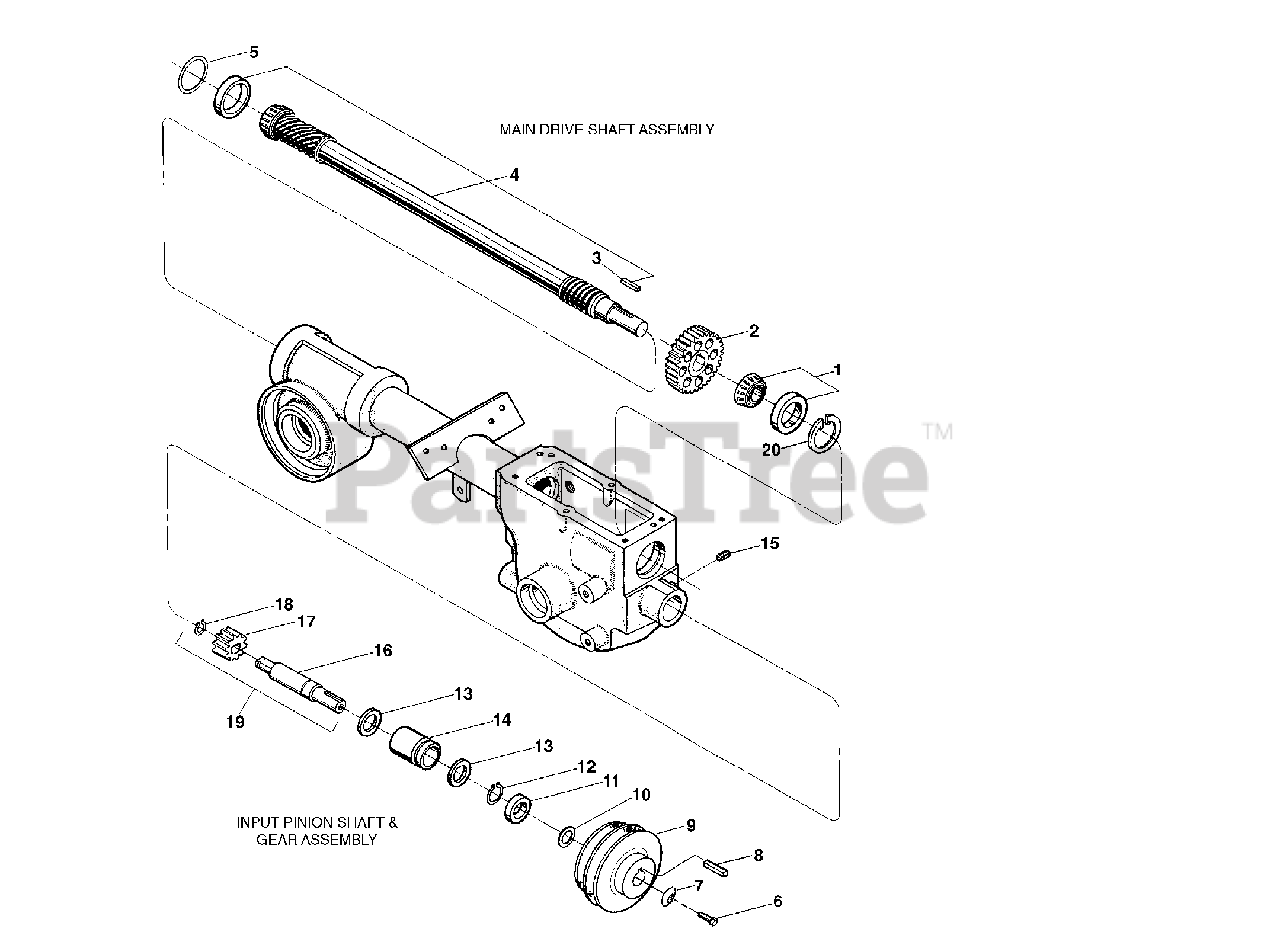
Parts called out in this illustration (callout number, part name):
1	Bearing, Tapered Roller with Race
2	Spur Gear
3	Key, 3/16 sq. x 1
4	Main Drive Shaft
5	Shim, Rear Bearing Cap, .010" thick
5	Shim, same as above, but .030" thick
5	Shim, same as above, but .005" thick
6	Hex Hd. Screw, 5/16-24 x 1-1/8
7	Washer, Disc Spring (concave surface faces pulley)
8	Key, 3/16 sq. x 1-1/2
9	Transmission Drive Pulley
10	Support Washer
11	Oil Seal, Input Pinion Shaft
12	Retaining Ring (external)
13	Thrust Washer
14	Bushing
15	Set Screw, 5/16-18 x 3/8
16	Input Pinion (steel shaft)
17	Input Pinion Gear
18	Retaining Ring (external) l
19	Pinion Assy.
20	Retaining Ring (internal)
